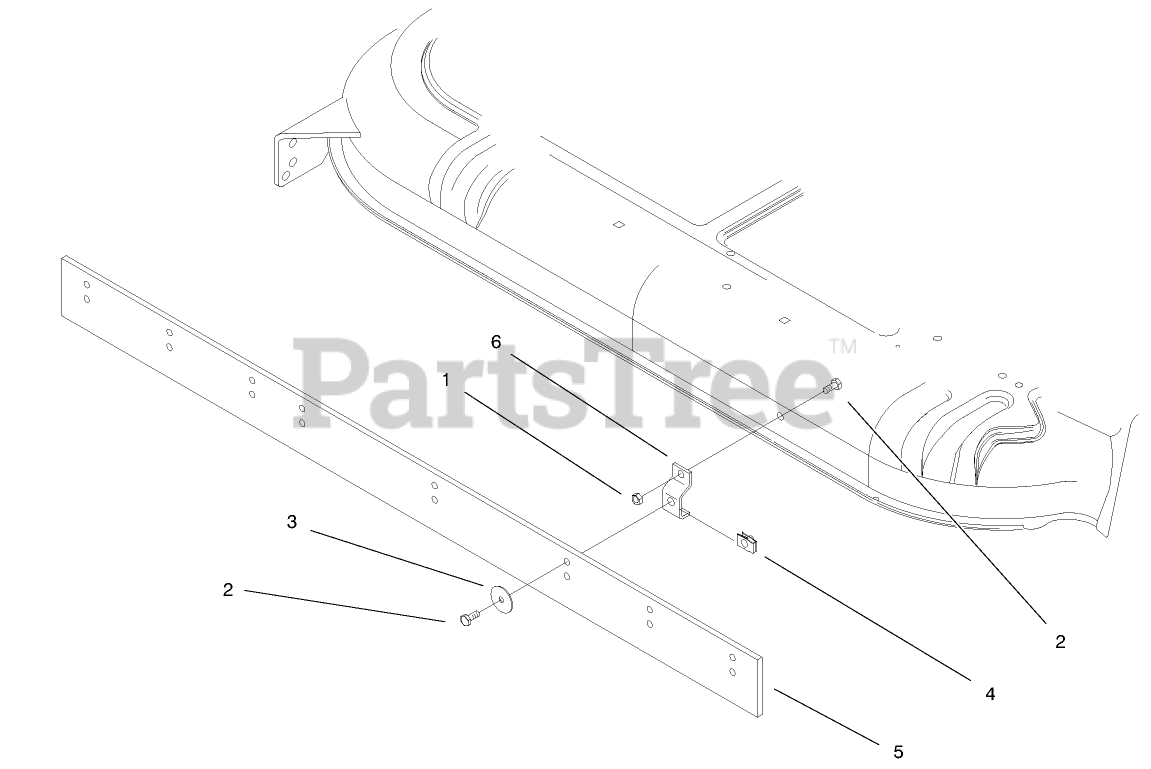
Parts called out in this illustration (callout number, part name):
1	NUT-LOCK, NI
2	SCREW-HH
3	WASHER-FLAT
4	NUT-SPEED
5	WIPER - STRIPING, 44/52
6	BRACKET - MOUNTING
